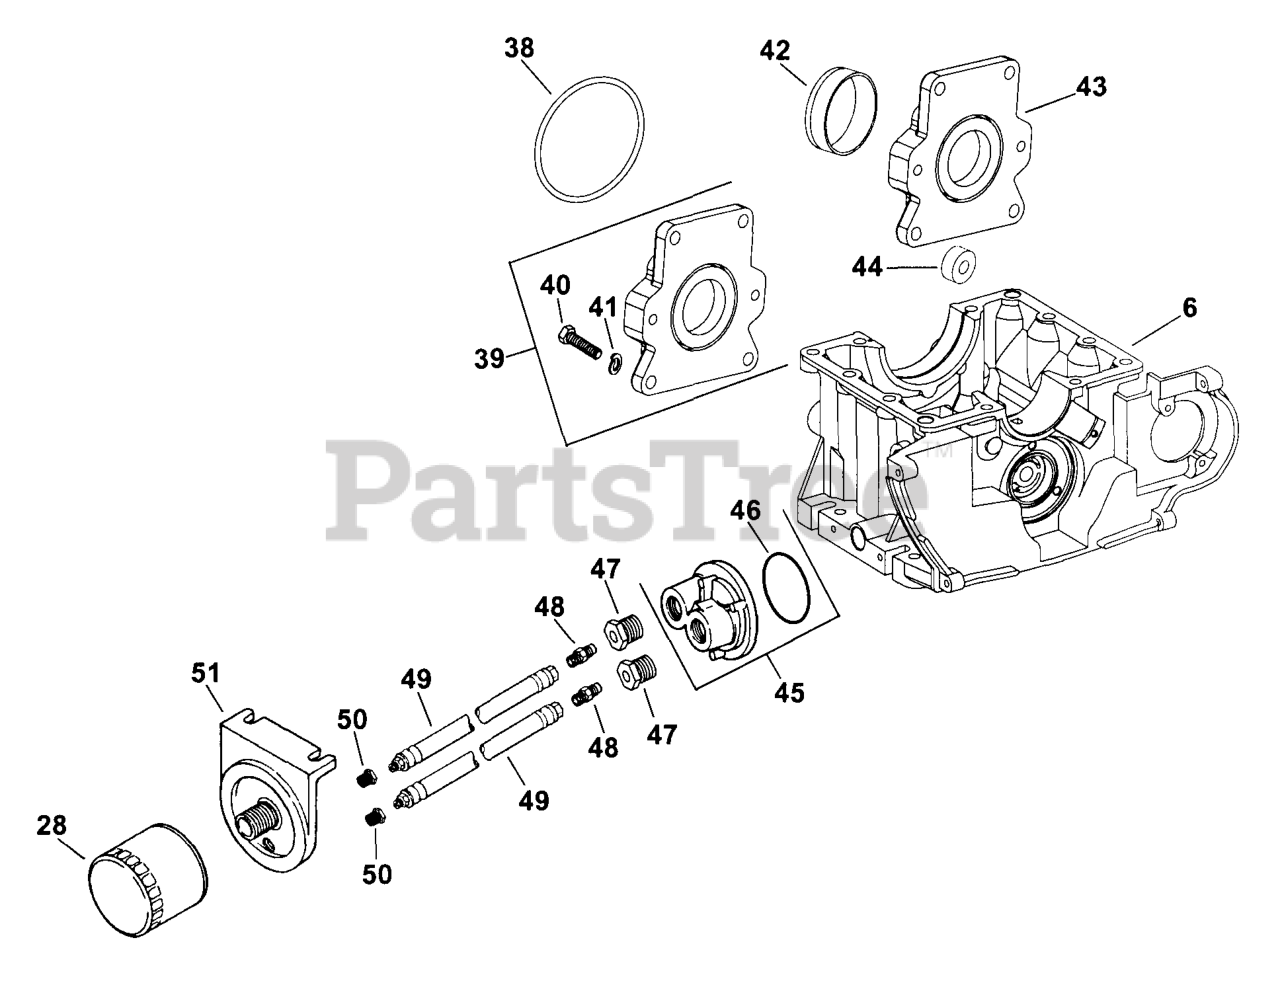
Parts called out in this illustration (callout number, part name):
6	CRANKCASE-LOWER ASSEMBLY
28	OIL FILTER
39	KIT, PUMP ADAPTER
40	SCREW,CAP HD 7/16-14x1 1/2"
41	WASHER, SPRING LOCK 7/16"
